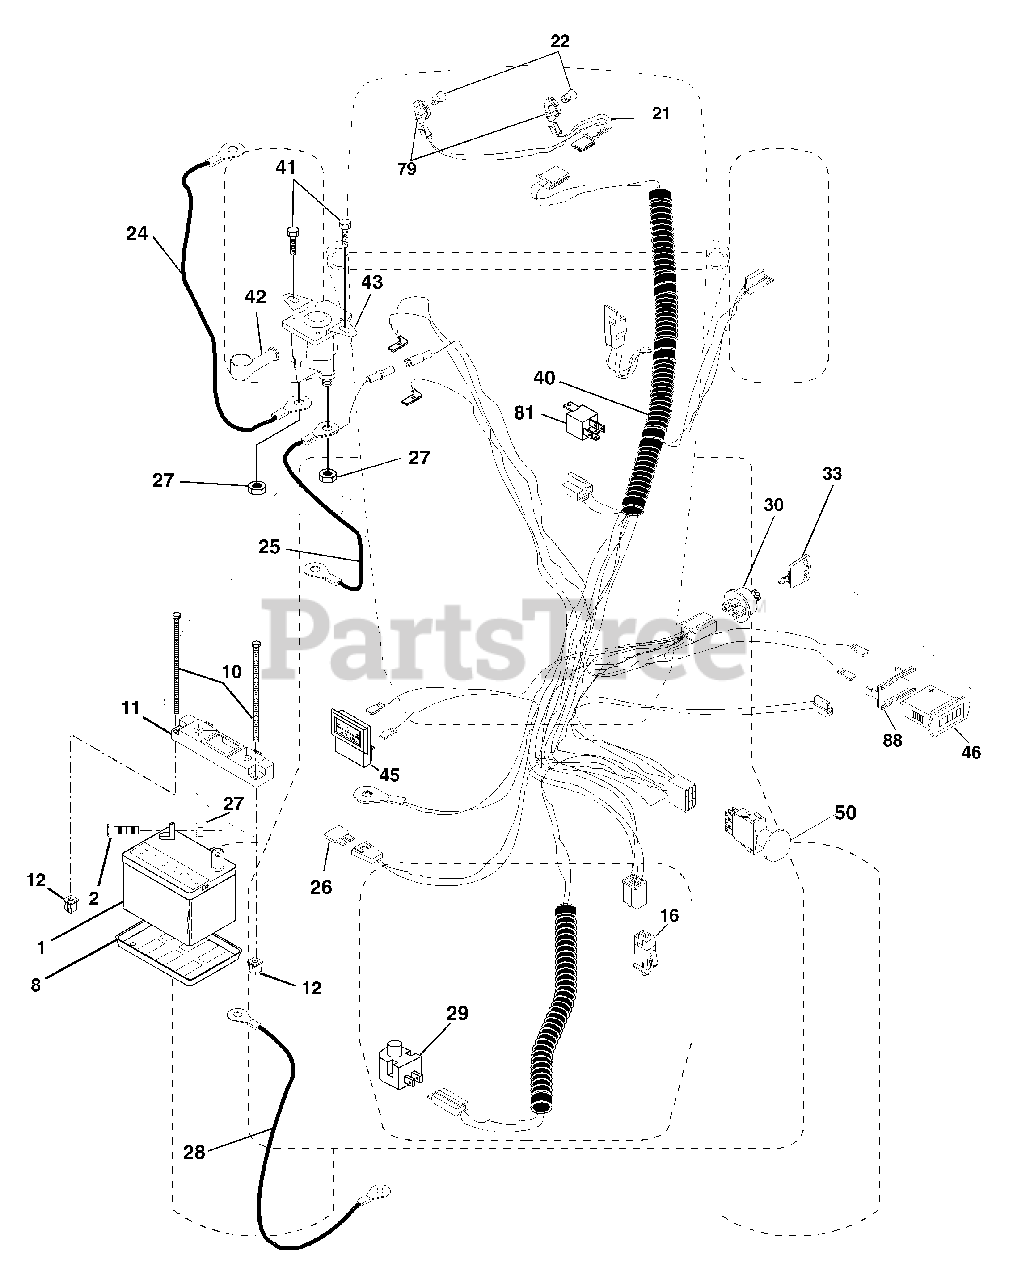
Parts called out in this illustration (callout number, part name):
1	Battery
2	Bolt Hex Head 1/4-20 x 3/4
8	Tray, Battery
10	Bolt Btr Frt 1/4-20 X 7.5 zinc
11	Holdown Battery Front Mount
12	Nut Push Nylon 1/4"
16	Switch Interlock Push-In
21	Harness Headlight w/Bulbs
22	Bulb Light
24	Cable, Battery
25	Cable, Battery
26	Fuse
27	Nut Keps Hex 1/4-20 Unc
28	Cable, Ground
29	Switch, Plunger
30	Switch, Ign
33	Key
40	Harness, Ignition
41	Screw 1/4-20 x 1/2
42	Cover, Terminal Red
43	Solenoid
45	Ammeter
46	Hourmeter Snap-In
50	Switch, PTO
79	Socket, Light Bulb
81	Relay Asm.
89	Bracket Snap-In
